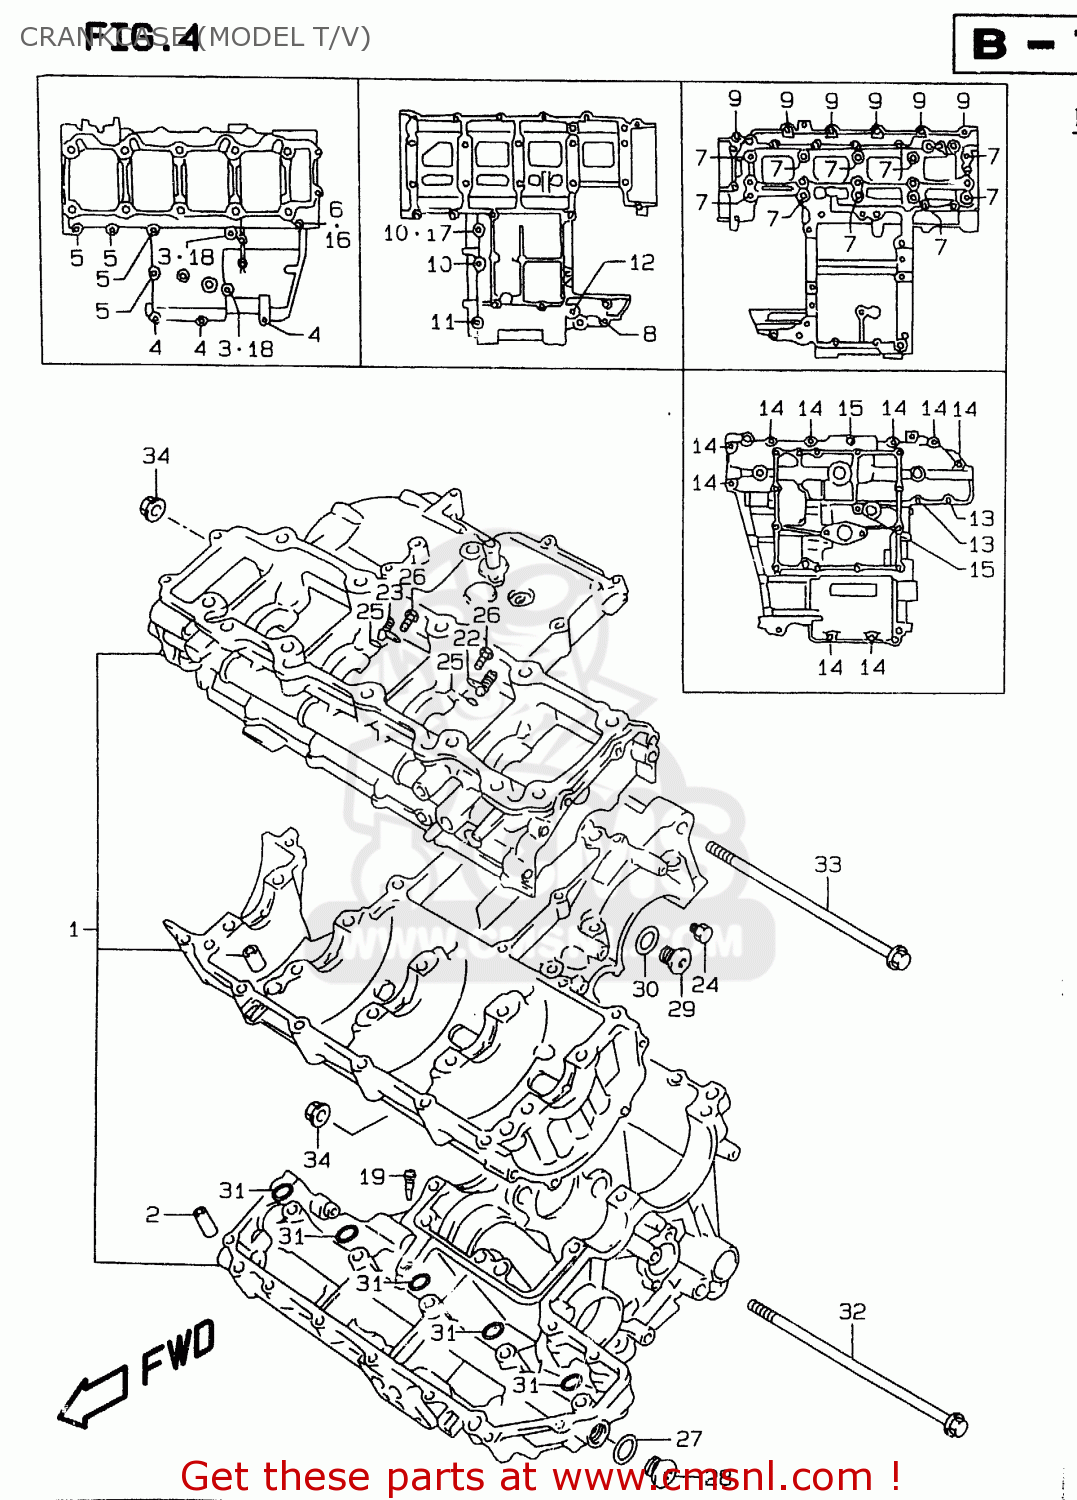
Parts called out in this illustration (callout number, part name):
1	CRANKCASE SET
2	PIN,CRANKCASE
3	BOLT(8X120)
4	BOLT
5	BOLT
6	BOLT
7	BOLT(9X95)
8	BOLT (6X45)
9	BOLT
10	BOLT
11	BOLT
12	BOLT
13	BOLT
14	BOLT
15	BOLT (6X90)
16	GASKET(5.8X11X1.2) (NAS)
17	GASKET(8.2X14X1) (NAS)
18	GASKET(8.2X14X1) (NAS)
19	JET(140)
20	BEARING,CRANK THRUST(GREEN)
21	BEARING,CRANK THRUST(RED)
22	JET,PISTON COOLINGR
23	JET,PISTON COOLING
24	JET,MAGNETO COOLING
25	O RING(D:1.2,ID:4)
26	BOLT(6X12)
27	GASKET(16X22X2) (NAS)
28	PLUG
29	PLUG,14X12
30	GASKET(14X20X1.5) (NAS)
31	O RING(D:1.9,ID:7.8)
32	BOLT(10X200)
33	BOLT(10X185)
34	NUT
